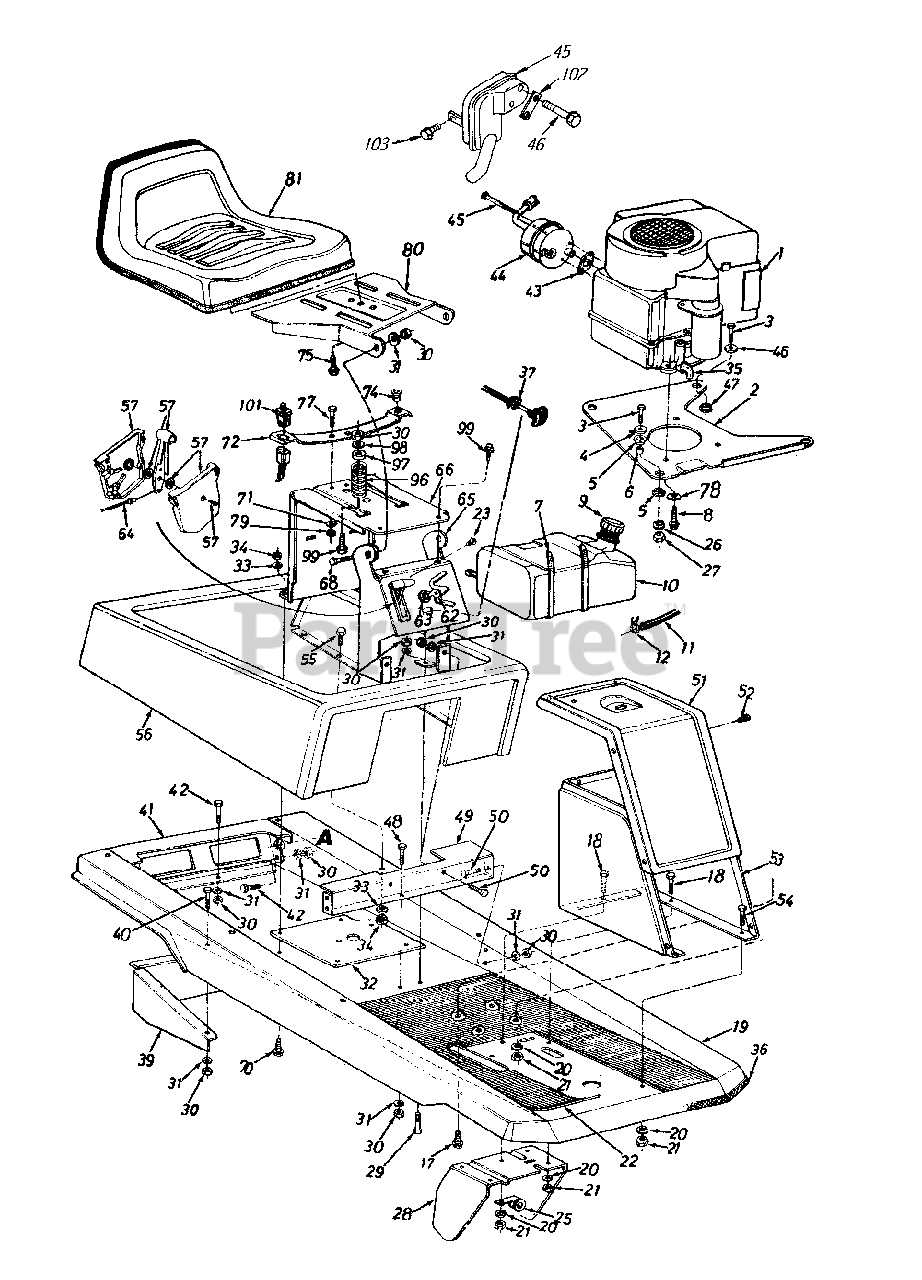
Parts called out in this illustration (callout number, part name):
1	Engine
4	Fl-Wash. .330" I.D. x 1.125" O.D.
5	Engine Mounting Grommet
6	Spacer .315" I.D. x .50" O.D. x .520" Lg.
7	Cable Tie 30.6 Lg.
8	Hex Wash. Hd. Self-Tap Scr. 3/8-16 x 1.25" Lg.
9	Gas Cap
10	Fuel Tank
11	Fuel Line-26" Lg.
12	Hose Clamp-1/2" O.D. Tube
17	Plastite Scr. 5/16 x 1.25" Lg.
18	Hex Bolt 5/16-18 x .75" Lg.
19	Main Frame
20	L-Wash. 5/16" I.D.
21	Hex Nut 5/16-18 Thd.
22	Floor Mat
23	Truss Mach. AB-Tap Scr.#10 x .50" Lg.
25	Clamp
26	L-Wash. 5/16" I.D.
27	Hex Nut 5/16-24 Thd.
28	Clutch-Brake Pedal Ass'y.
29	Hex Bolt 5/16-18 x .75" Lg
30	Hex Nut 5/16-18 Thd.
31	L-Wash. 5/16" I.D.
34	Hex Nut 1/4-20 Thd.
35	90° Elbow Male To Female
36	Trim Strip
37	Choke Control
43	Exhaust Gasket (B&S)
44	Muffler Ass'y. (B&S)
45	Shld. Bolt (B&S)
46	Fl-Wash. .330" I.D. x 1.25" O.D.
47	Flange Wash. .320" I.D. x .750" O.D.
49	Seat Support & Frame Brkt.
50	Hex Bolt 5/16-18 x .75" Lg.
55	Hex Bolt 1/4-20 x .50" Lg.
62	Ignition Key
63	Ignition Switch
64	Throttle Control Wire 35" Lg.
65	Front Seat Bracket
70	Hex Tap Scr. 1/4-20 x 1.0" Lg.
71	L-Wash. 5/16" I.D.
72	Seat Spring
74	Grommet
75	Hex Bolt 3/8-16 x .62" Lg. (Gr. 5)
77	Hex Bolt 5/16-18 x .75" Lg.
78	Bell-Wash. .345" I.D. x .88" O.D.
79	Hex Cent. L-Nut 5/16-18 Thd.
81	Seat Ass'y. Comp.
96	Compression Spring 2.7" Lg.
97	Bushing
98	Fl-Wash. .344" I.D. x .875"
99	Hex Bolt 5/16-18 x 1" Lg. (Gr. 5)
101	Seat Switch
102	Locking Plate
103	Screw 1/4-20: 5/8" Lg.
